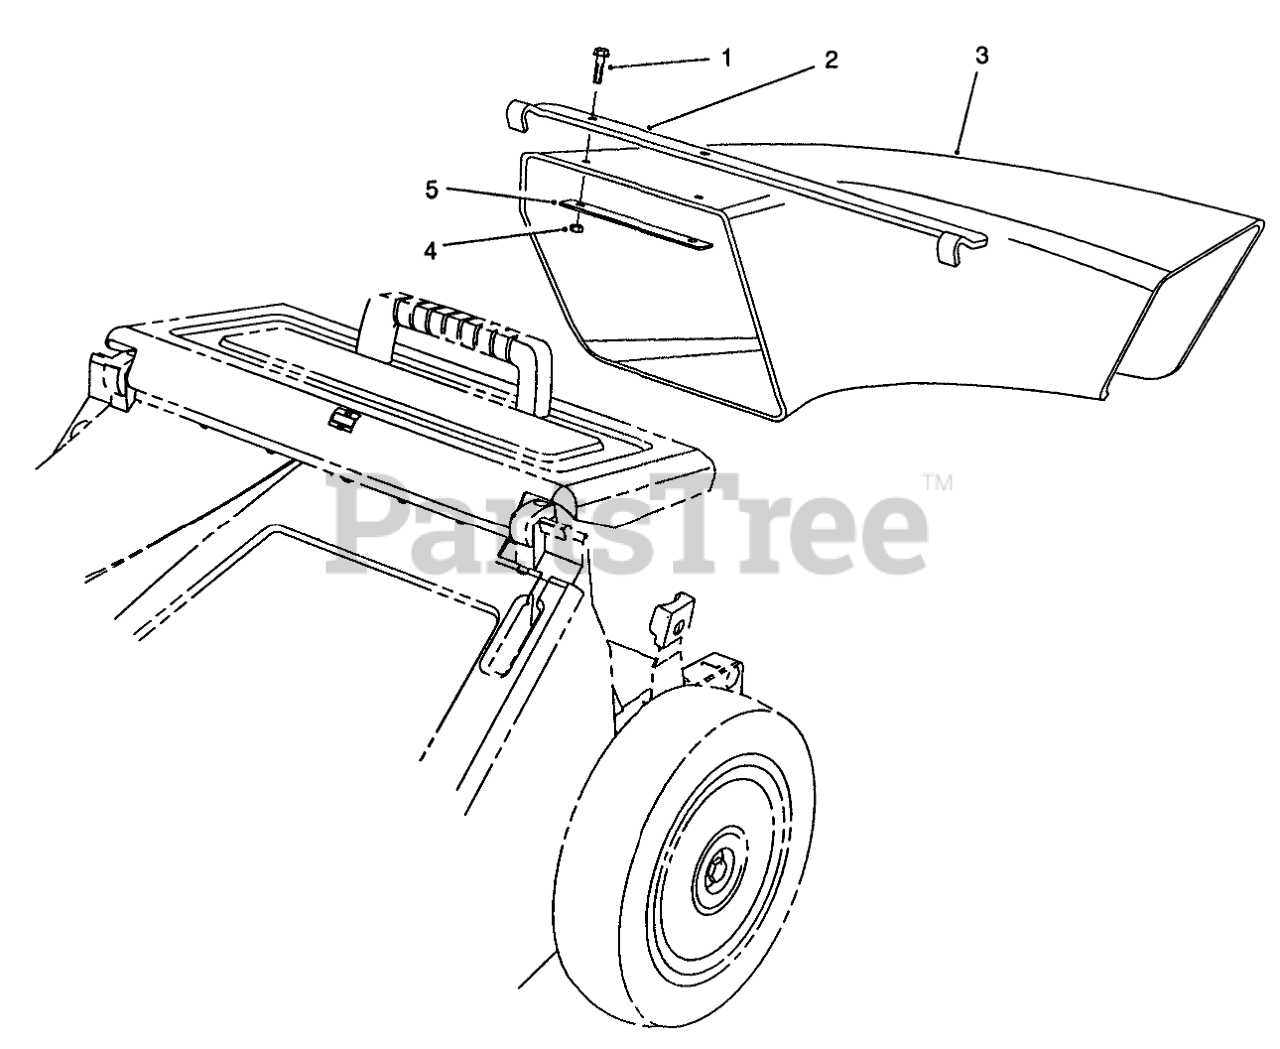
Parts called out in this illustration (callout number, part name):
1	SCREW-HWH
2	CHUTE HANGER BRACKET
3	Chute-Discharge
4	NUT-LOCK, NI
5	STRESS PLATE
